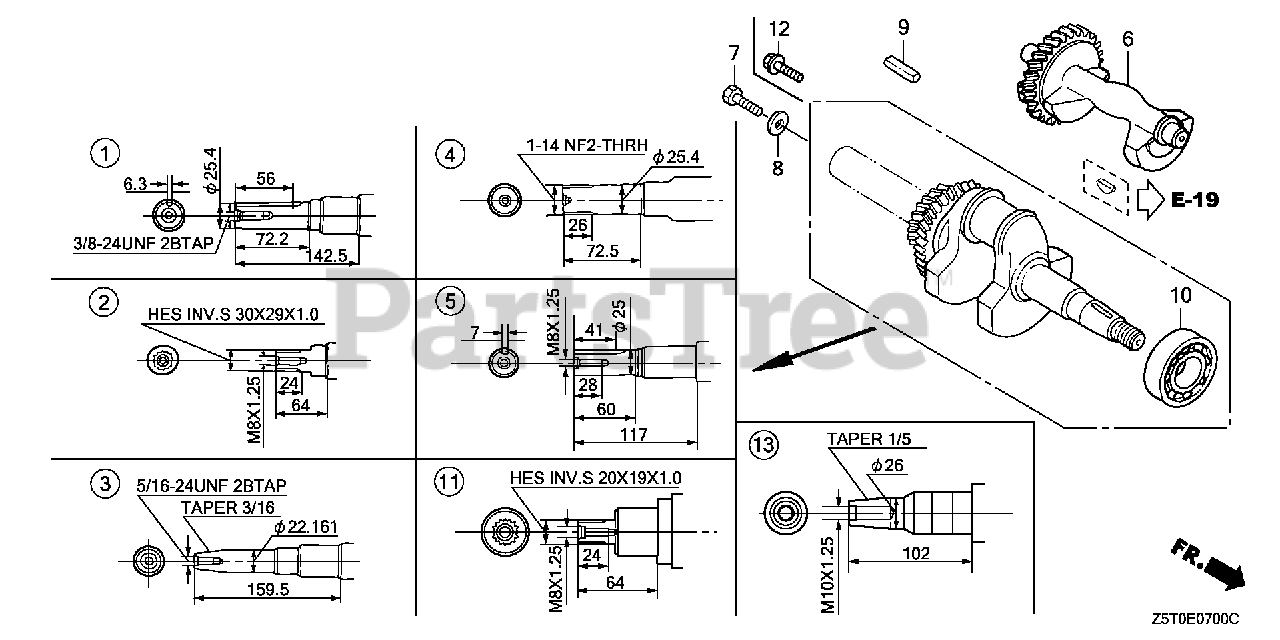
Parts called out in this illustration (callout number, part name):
1	CRANKSHAFT
6	WEIGHT, BALANCER
9	KEY (6.3X6.3X43)
10	BEARING, RADIAL BALL (6207SH)
